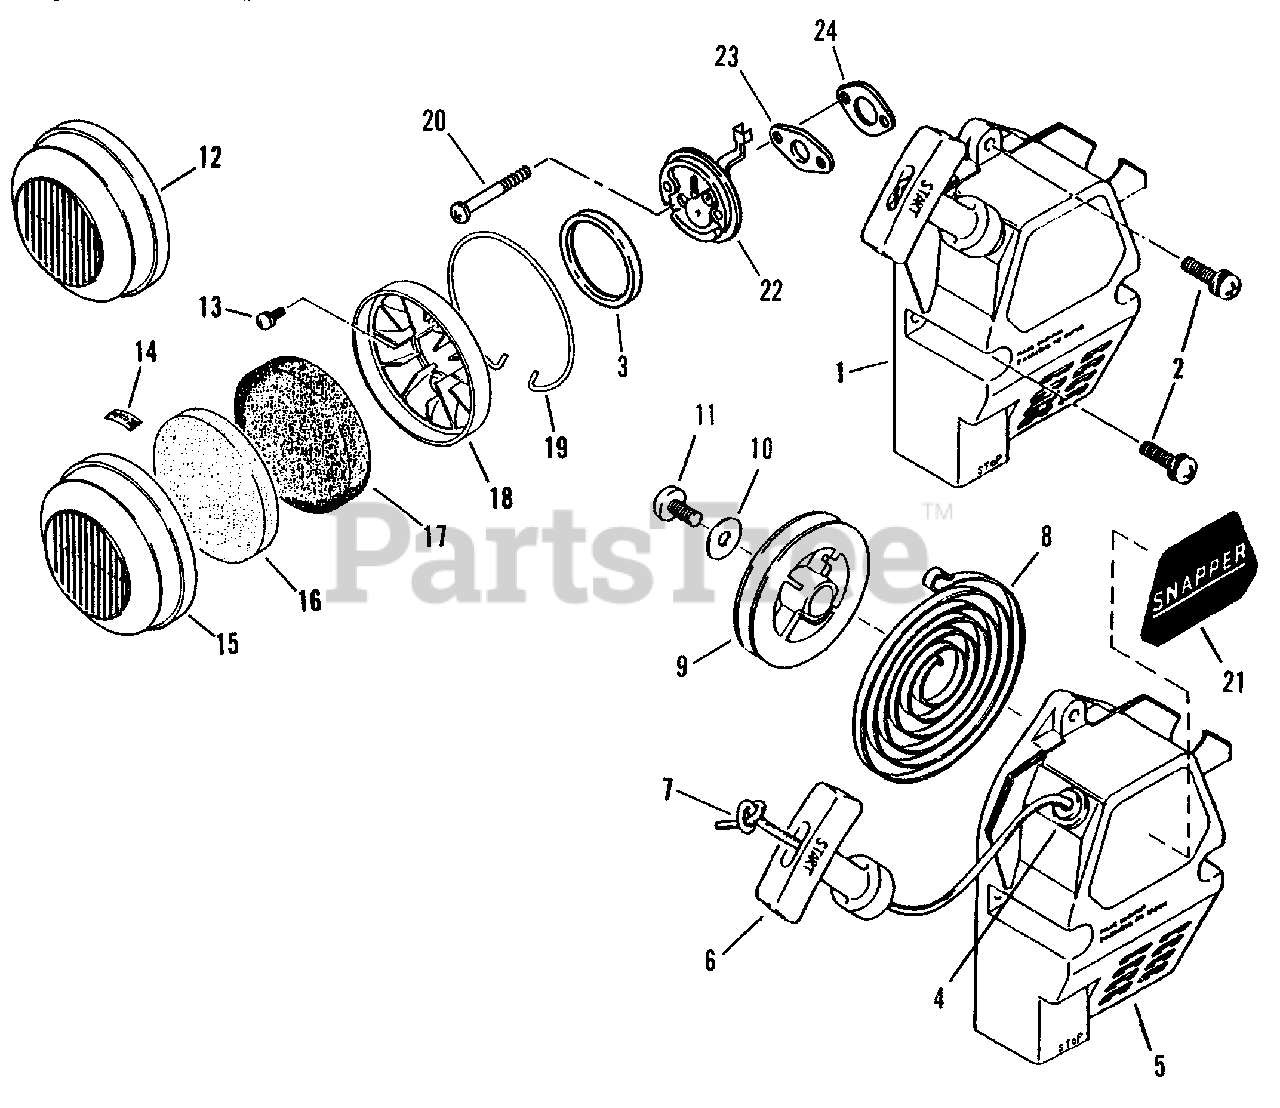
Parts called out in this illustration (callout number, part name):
1	RECOIL STARTER ASSM'Y.
2	SCREW/WASHER
3	"O"-RING
5	HOUSING, Starter
6	KNOB, Starter
7	ROPE, Starter
8	SPRING, Spiral
12	ASSEMBLY, Air Cleaner
13	SCREW/WASHER
14	LABEL, Choke
15	COVER, Cleaner
16	ELEMENT, Cleaner
17	ELEMENT, Cleaner
18	CASE, Cleaner
20	SCREW/WASHER
21	LABEL, Snapper
22	BRACKET, Choke
